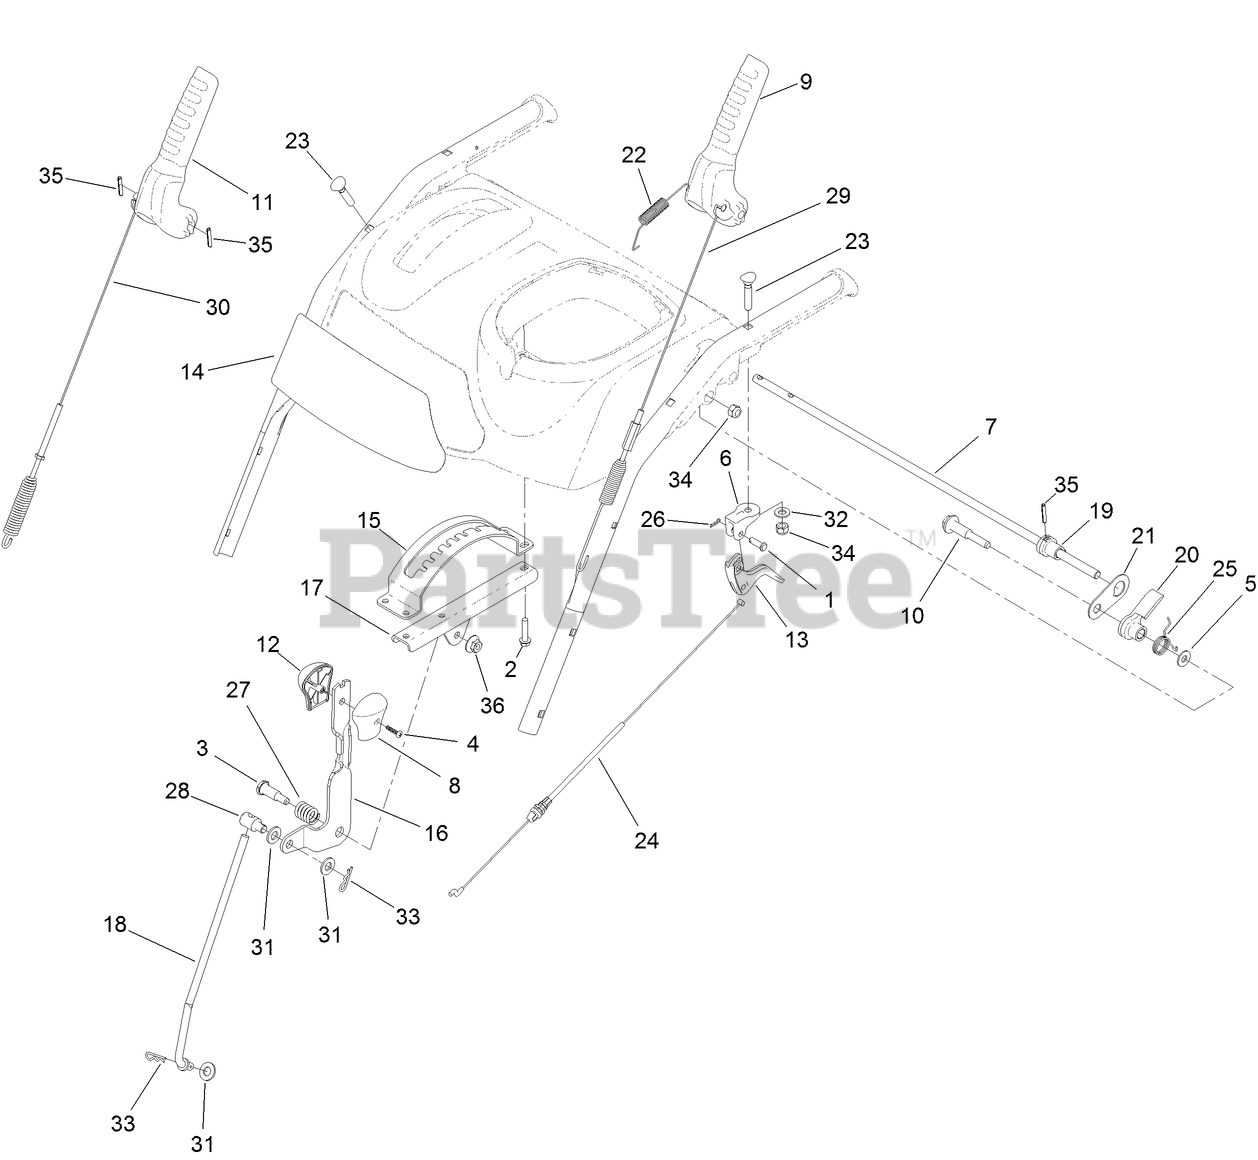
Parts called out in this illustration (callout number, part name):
1	PIN-CLEVIS
2	SCREW-PLASTITE
3	SCREW-SHOULDER
4	SCREW-PPH
5	WASHER-FLAT
6	MOUNT-CLUTCH, LEVER
7	ROD-LOCKOUT
8	KNOB-SHIFT, LH
9	LEVER-TRACTION
10	SCREW-SHOULDER
11	LEVER-AUGER
12	KNOB-SHIFT, RH
13	LEVER-CLUTCH
14	DECAL-CONTROL PANEL
15	GUIDE-SELECTOR, SPEED
16	SELECTOR-SPEED
17	BRACKET-SELECTOR, SPEED
18	ROD-SHIFT
19	CAM-LOCKOUT
20	LATCH-LOCKOUT
21	LINK-LOCKOUT
22	SPRING-TENSION
23	SCREW-HANDLE
24	CABLE-CLUTCH
25	SPRING-TORSION
26	PIN-HAIR
27	SPRING-COMPRESSION
28	TRUNNION-ROD
29	CABLE-TRACTION
30	CABLE-AUGER
31	WASHER-FLAT
32	WASHER-FLAT
33	PIN-COTTER
34	NUT-LOCK, NI
35	PIN-SPRING
36	NUT-HF
